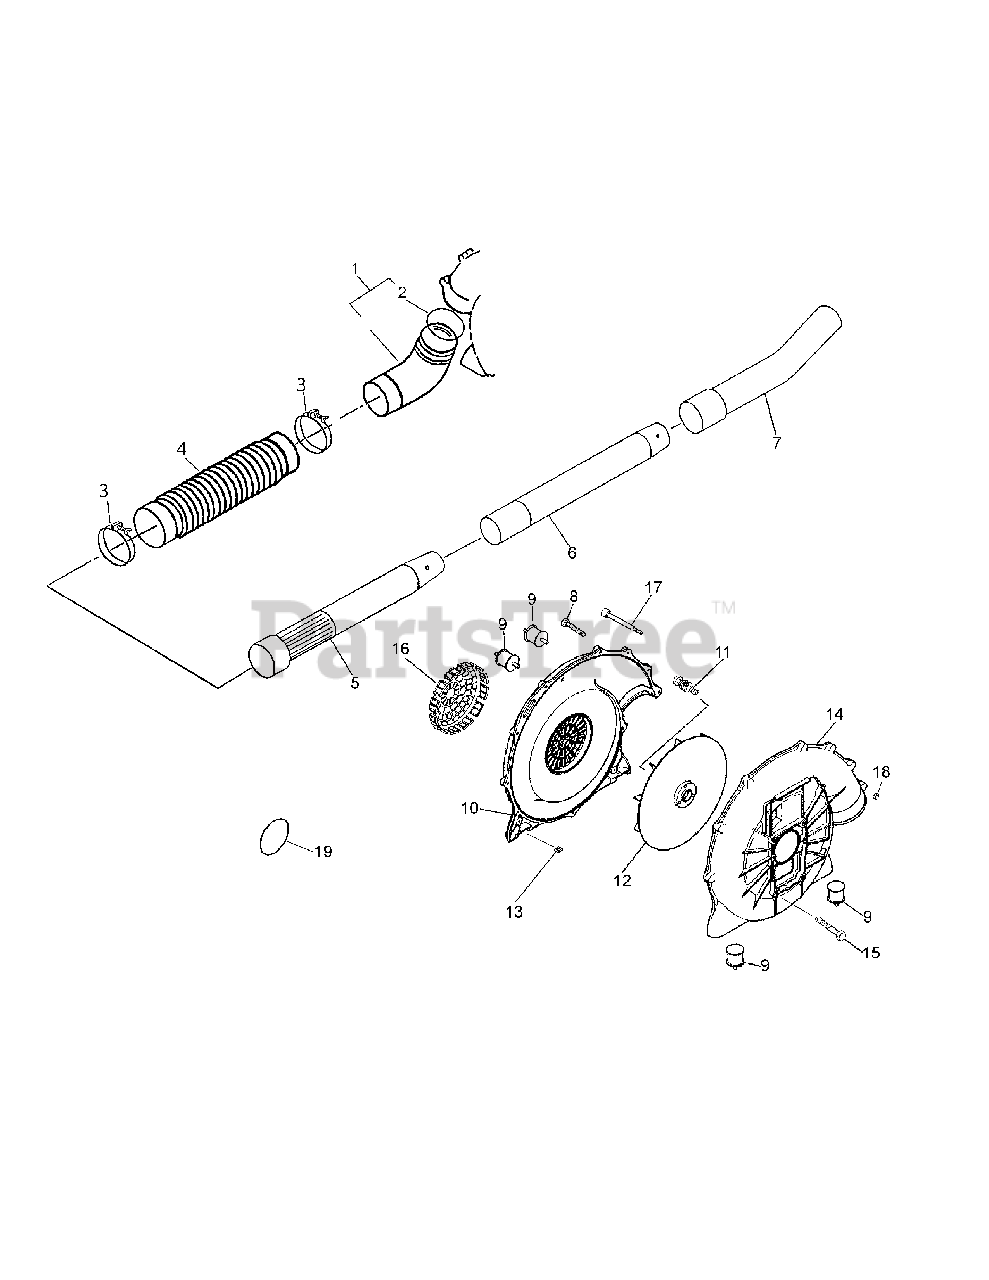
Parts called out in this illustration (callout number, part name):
1	ELBOW PIPE C.P.
8	TAPPING SCREW M5x20
9	VIBRO-ISOLATING RUBBER
11	PRE-COAT LOCK BOLT
15	PRE-COAT LOCK BOLT
17	SOCKET SCREW M6x65
18	NYLON NUT M6
